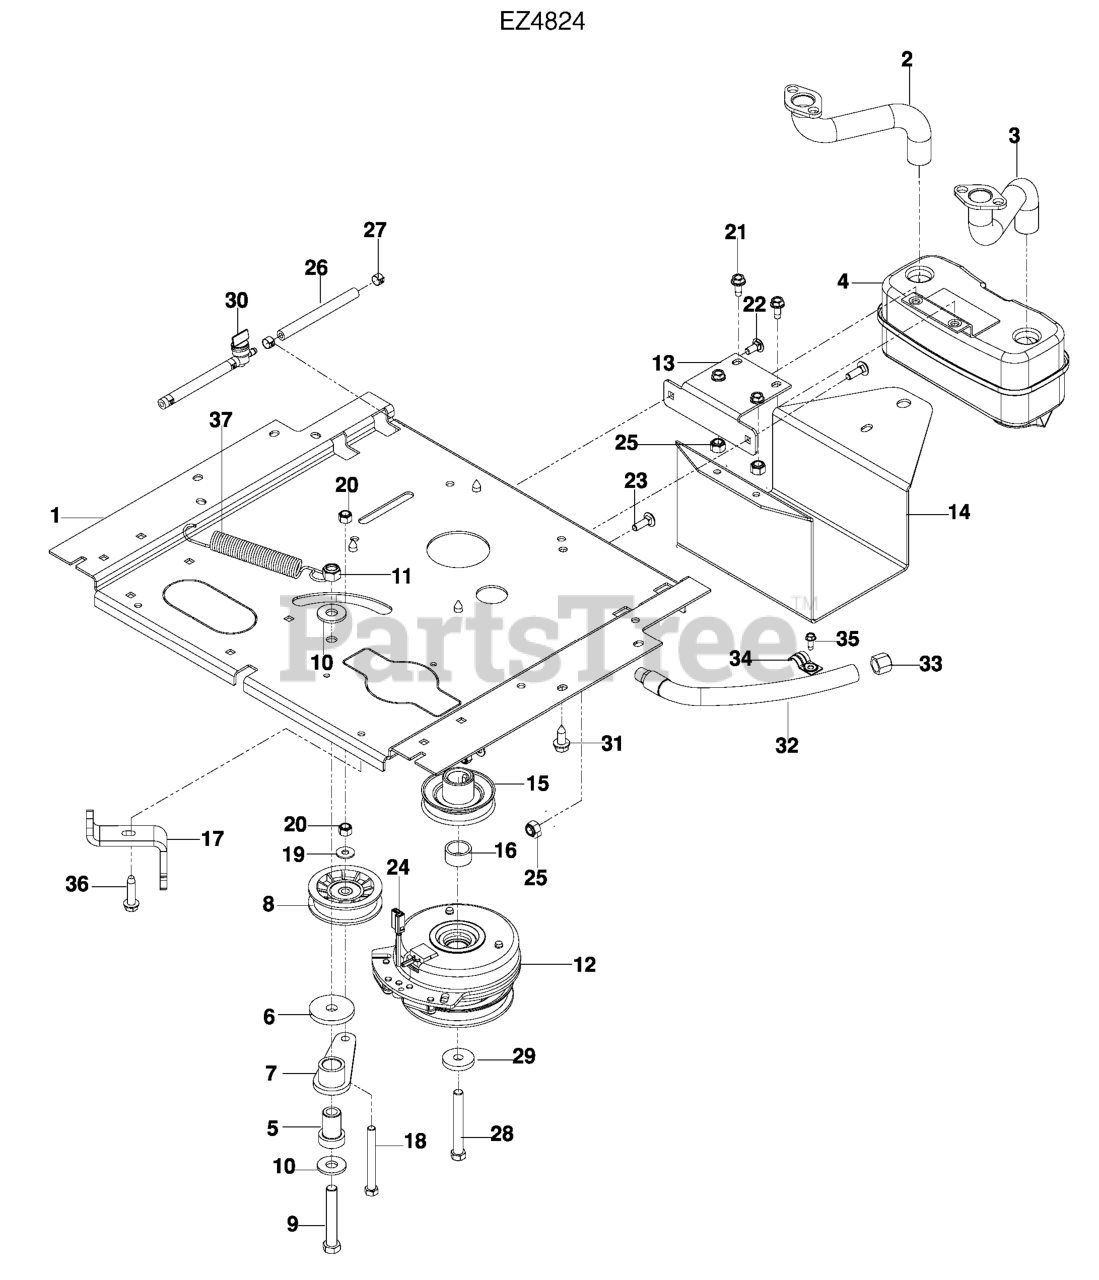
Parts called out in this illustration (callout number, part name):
1	PLATE, ENGINE, BLACK
2	RP.EXHAUST.TUBE.LH.BS/TWIN
3	EXHAUST.TUBE.RH.BS/TWIN
4	MUFFLER ASM TWIN
5	IDLER SPINDLE
6	HEAVY WASHER
7	RP.IDLER ARM WELDMENT
8	PULLEY, IDLER RAKE & ZTR
9	HCS 1/2C X 3 1/4
10	WASH USS FLAT 1/2
11	NUT 1/2-13 HEX NYLOC ZD
12	CLUTCH, 105 FT-LBS
13	BRACKET, MUFFLER, BLACK
14	GUARD, MUFFLER, BLACK
15	PULLEY, ENGINE
16	T & B SPACER
17	STOP, CLUTCH BLK
18	HCS 3/8-16X3 1/2 GR5
19	WASHER 5/16 FLAT
20	NUT 3/8-16 NYLOC
21	BOLT 5/16-18 X 3/4
22	BOLT 5/16C X 3/4" CARRIAGE
23	RHSNB 5/16C X 1
24	CLUTCH HARNESS
25	5/16-18 NYLOC FLANGE NUT
26	FUEL LINE 5"
27	HOSE CLAMP
28	HCS 7/16-20X3-1/2 GR 5 ZN
29	CLUTCH, WASHER
30	FUEL VALVE
31	HHFS 3/8-16 X 1.0 THD FORMING
32	OIL DRAIN HOSE
35	SCREW 1/4 X 5/8
36	BOLT 3/8-16 X 1 1/2 ZINC CLEAR
37	SPRING, DECK DRIVE
